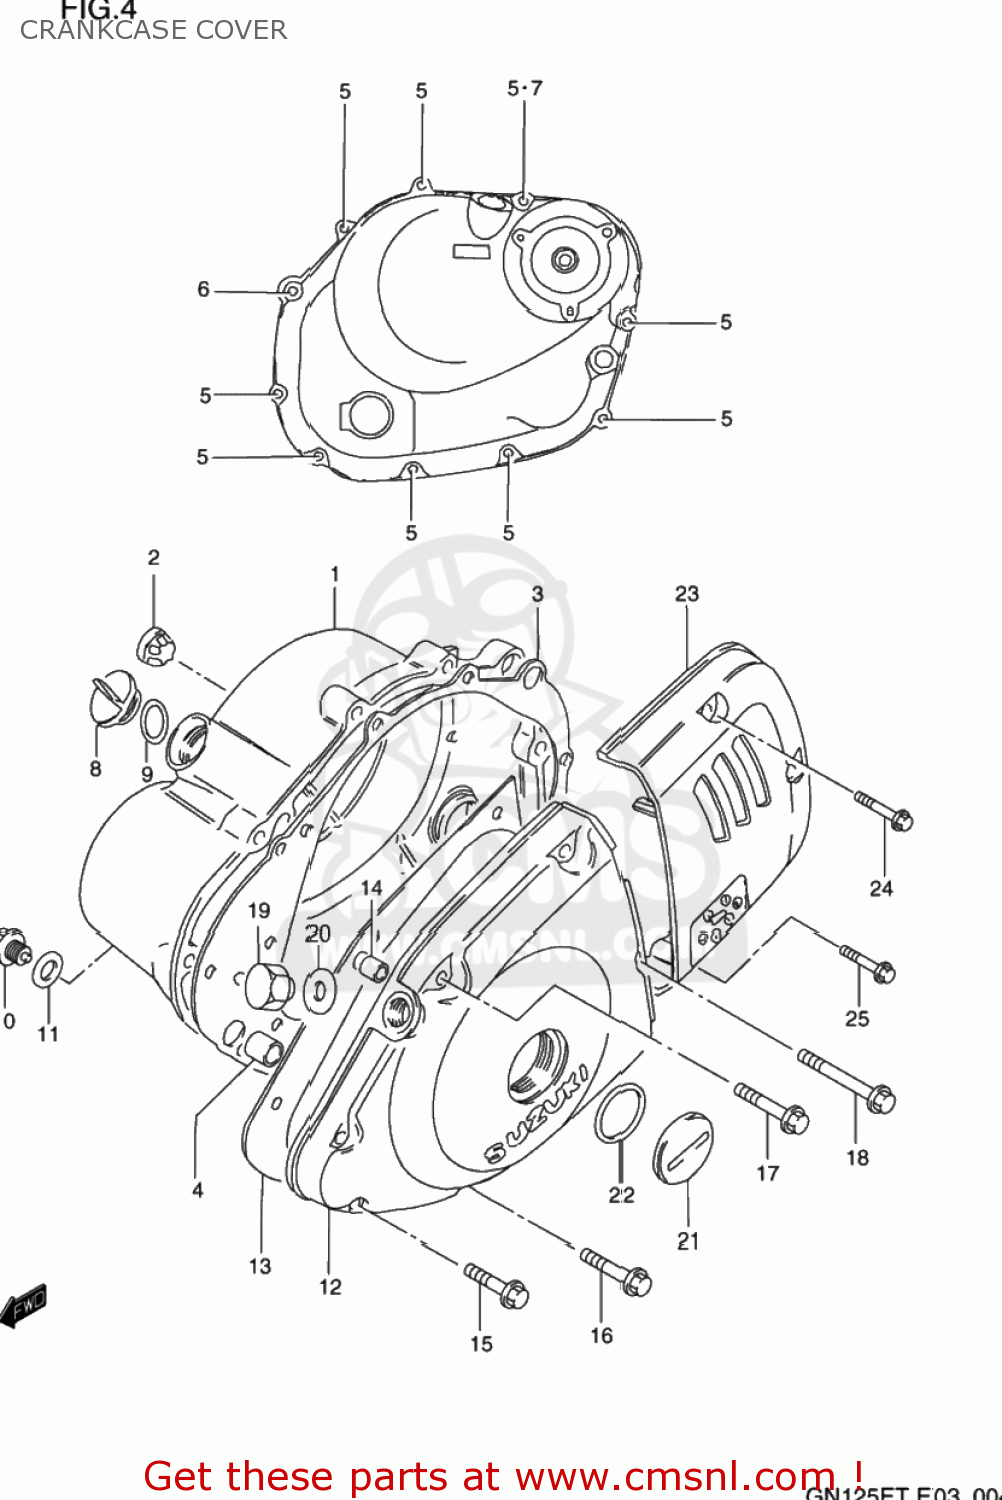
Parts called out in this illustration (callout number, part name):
1	COVER,CLUTCH
2	LENS,OIL LEVEL CHECK
3	GASKET,CLUTCH COVER (NAS)
4	PIN
5	BOLT
6	BOLT
7	GASKET(5.8X13X1.2) (NAS)
8	PLUG(20X10)
9	O RING(D:3.1,ID:16.8)
10	PLUG(14X12)
11	GASKET(13.8X18.8X4.8) (NAS)
12	COVER,MAGNETO
13	GASKET,MAGNETO COVER (NAS)
14	PIN
15	BOLT
16	BOLT
17	BOLT
18	BOLT
19	PLUG,12X9
20	GASKET(12.1X16.2X3.7) (NAS)
21	PLUG
22	O RING(D:3.1,ID:22.7)
23	COVER,SPROCKET
24	BOLT
25	BOLT
